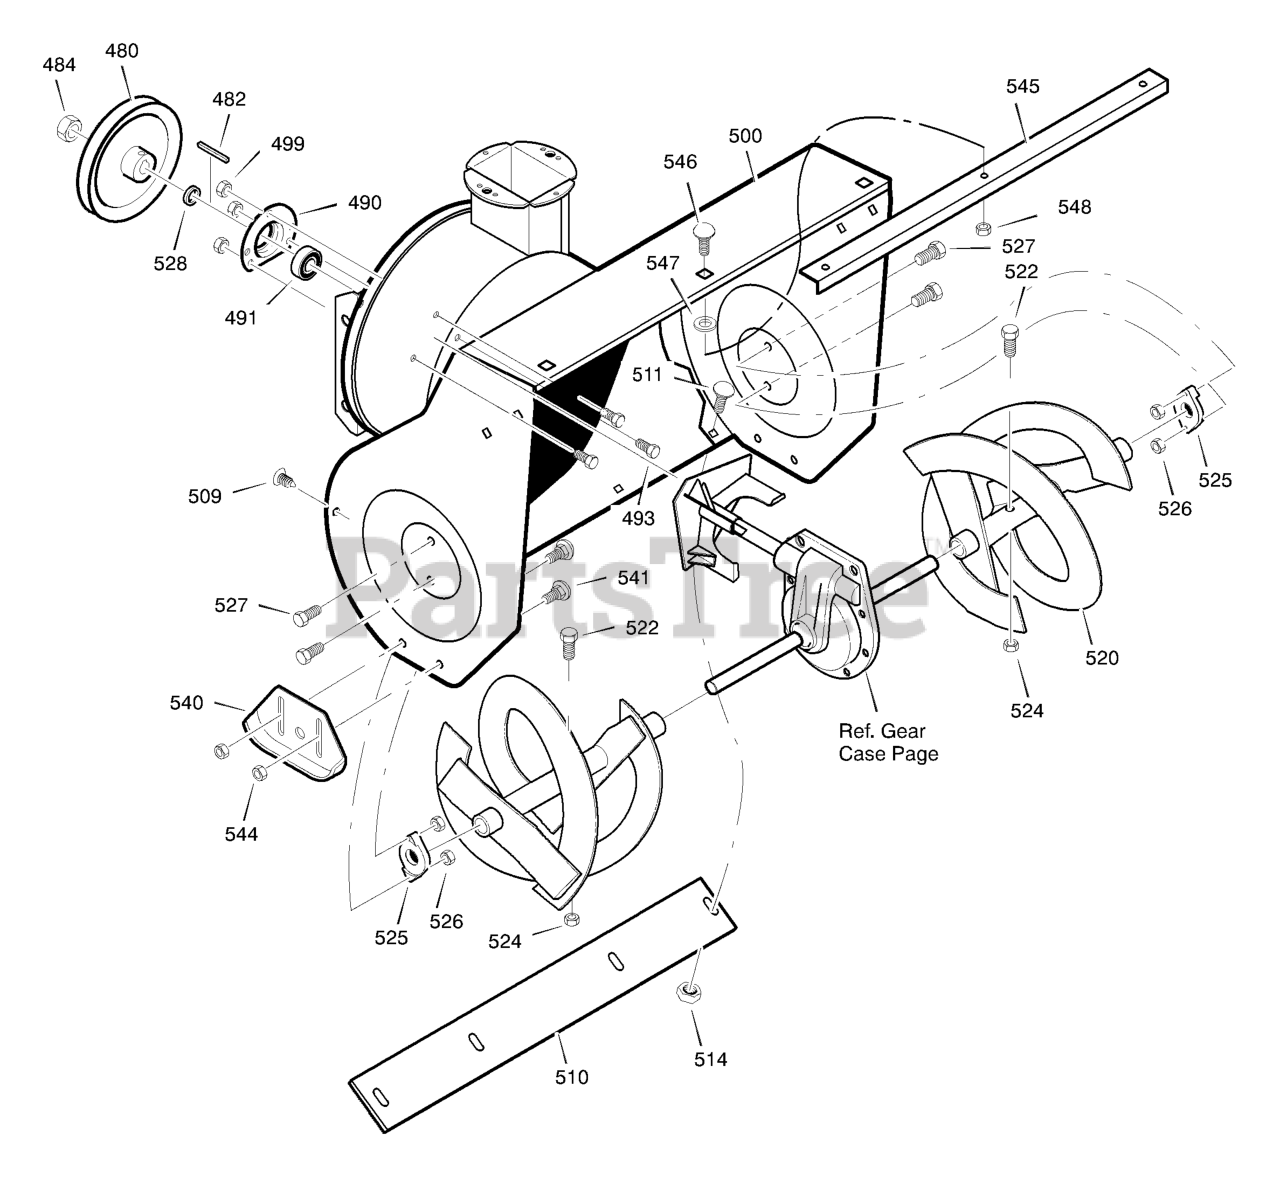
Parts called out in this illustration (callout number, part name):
482	KEY, SQUARE
484	NUT, 1/4-20
485	SPACER, FRICTION PULLEY
490	RETAINER, BALL BRNG
491	BEARING, BALL
493	BOLT, HEX - 0.31-18X0.50
499	NUT, 5/16-18 HEXWDFLLK
500	HOUSING, ASSY
509	PLUG, CHRISTMAS TREE
510	BLADE, SCRAPER
511	BOLT, CARRIAGE
520	AUGER, ASSY, LH
521	AUGER, ASSY, RH
522	BOLT
524	NUT, 5/16-18
525	BEARING,FLANGE
527	SCREW, 5/16-18 x 0.75
536	BOLT
540	SKID, HEIGHT ADJUST
541	BOLT, 5/16-18 X .75
544	NUT, 5/16-18 REGHEX
545	STIFFENER, AUG HSG
546	BOLT, CARR.
547	WASHER
